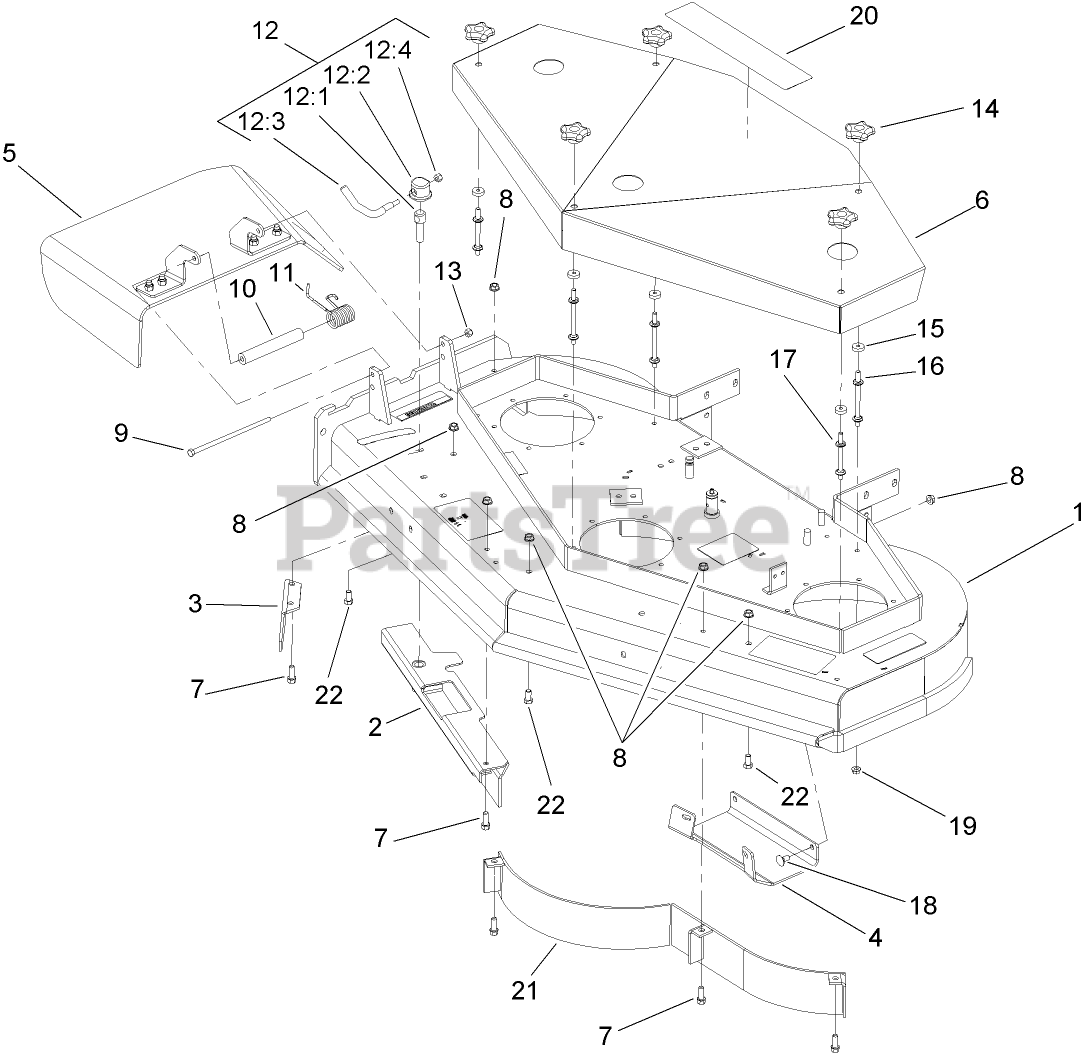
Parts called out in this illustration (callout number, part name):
1	DECK ASM
2	BAFFLE-ADJUSTABLE
3	BAFFLE-DISCHARGE
4	Plate-Skid
5	DEFLECTOR ASM
7	SCREW-HWH
8	NUT-HHF, WHIZ
9	SCREW-HH
10	SPACER
11	SPRING-TORSION
12	LEVER ASM
12:1	Screw-Lock
12:2	CAP-LOCK
12:3	Lever-Lock
12:4	NUT-LOCK, NI
13	NUT-LOCK, NI
14	KNOB-HANDLE
15	WASHER
16	STUD-SHIELD, BELT (LONG)
17	STUD-SHIELD, BELT (SHORT)
18	SCREW-CARR
19	NUT-HF
20	DECAL
21	BAFFLE ASM
22	SCREW-HH
